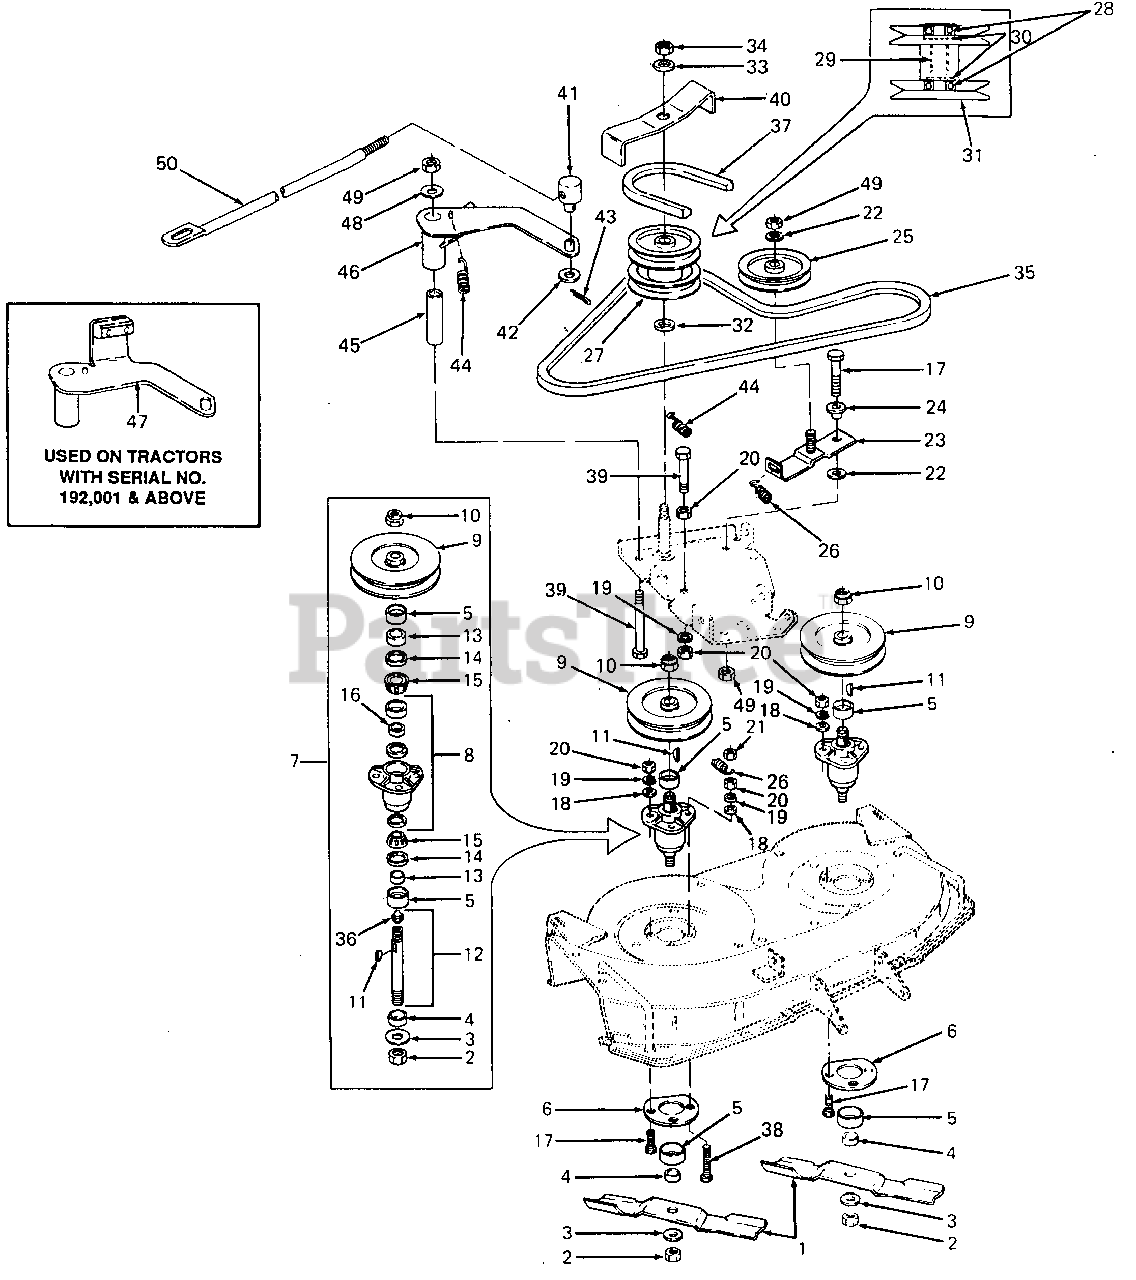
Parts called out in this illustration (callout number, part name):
1	Blade, Low Lift, 19.38 Lg
2	Nut, Hex, 3/4-16 GR8
3	Washer, Flat, .781 X 2.0 X .105 Thk HDN
4	Spacer, Blade
5	Cup, Spindle HDN
6	Plate, Spindle Mounting
7	Spindle Service Kit
8	Housing, Spindle w/Cups
9	4L V-Pulley, 4.62 OD X 0.75 ID
10	Nut, Hex Jam, 3/4-16
11	Key, #91 Woodruff, 1/4 X 3/4 HDN
12	Kit, Shaft w/Seal
13	Spacer, .755 X 1.25 X .44 Lg
14	Seal, Oil, 1.25 X 1.874 X .25
15	Cone, Bearing
16	Spacer, Bearing
17	Screw, Hex Cap, 3/8-16 X 1.25 GR5
18	Washer, Flat, .378 X 1.0 X .127 Thk
19	Washer, Lock, 3/8 Dia
20	Nut, Hex, 3/8-16 GR5
21	Nut, Hex Center Lock Jam, 3/8-16
22	Washer, Flat, .385 X .88 X .06 Thk HDN
23	Bracket, Idler
24	Spacer, Shld
25	Pulley, Flat Idler
26	Spring, Extension, .62 OD X 5.50 Lg
27	Pulley Assy, Double
28	Bearing, Ball, .62 ID X 1.38 OD X .44 Thk
29	Spacer, Pulley, .64 ID X .81 OD X 2.25 Lg
30	Snap Ring, Internal
31	Pulley, Double
32	Washer, Flat, .625 ID X 1.0 OD X .06 Thk HDN
33	Washer, Flat, .510 ID X 1.12 OD X .100 Thk HDN
34	Nut, Hex Patch Jam, 1/2-20
35	V-Belt, 1/2 X 63" Lg - A Full
36	Fitting, Lube, 3/16
37	V-Belt, PTO Drive
38	Screw, Hex Cap, 3/8-16 X 1.75 Lg GR5
39	Screw, Hex Cap, 3/8-16 X 2.5 Lg GR5
40	Guard, Belt
41	Ferrule
42	Washer, Flat, .406 X .875 X .06 Thk
43	Pin, Cottter, 3/32 Dia X .75 Lg
44	Spring, Extension, .75 OD X 5.31 Lg
45	Tube, Spacer
47	Arm Assy, Brake
48	Washer, Flat, .406 X .75 X .063 Thk
49	Nut, Hex Center Lock, 3/8-16 GR5
50	Rod, Deck Brake
